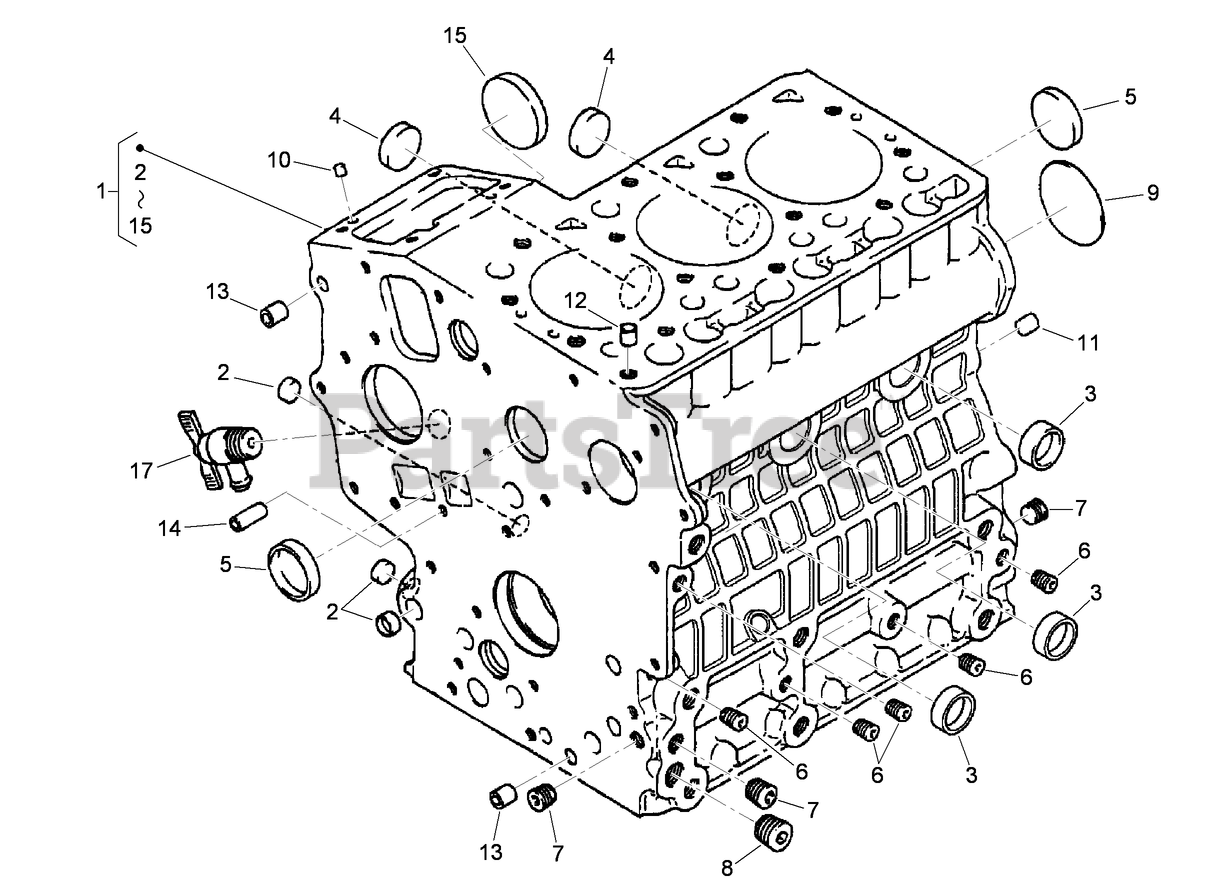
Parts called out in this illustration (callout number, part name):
1	CRANKCASE ASM
2	CAP-SEALING
3	CAP-SEALING
4	CAP-SEALING
5	CAP-SEALING
9	PLUG-EXPANSION
10	PIN-STRAIGHT
11	PIN-STRAIGHT
12	PIN-PIPE
13	PIN-PIPE
14	PIN-PIPE
15	COVER-FUEL, CAMSHAFT
17	DRAIN COCK ASM
